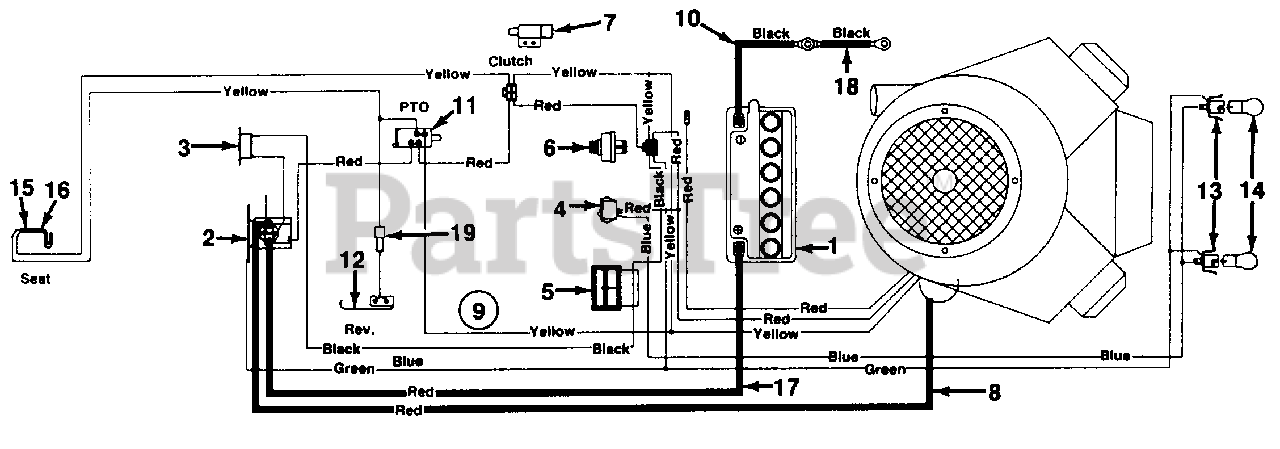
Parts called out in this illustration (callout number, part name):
1	BaKery-1 2V
2	Solenoid
3	Circuit Breaker
4	Light Switch
5	Ammeter
6	Ignition Switch
7	Safety Switch
8	Electric Wire-30.0" Lg.
9	Wire Harness
10	Ground Wire 11.5" Lg.
11	Safety Switch
12	Safety Switch
13	Headlight Socket
14	Headlight Bulb
15	Safety Switch
16	Safety Switch
17	Electric Wire-27" Lg.
18	Ground Wire-7.5" Lg.
19	Ext. Wire
